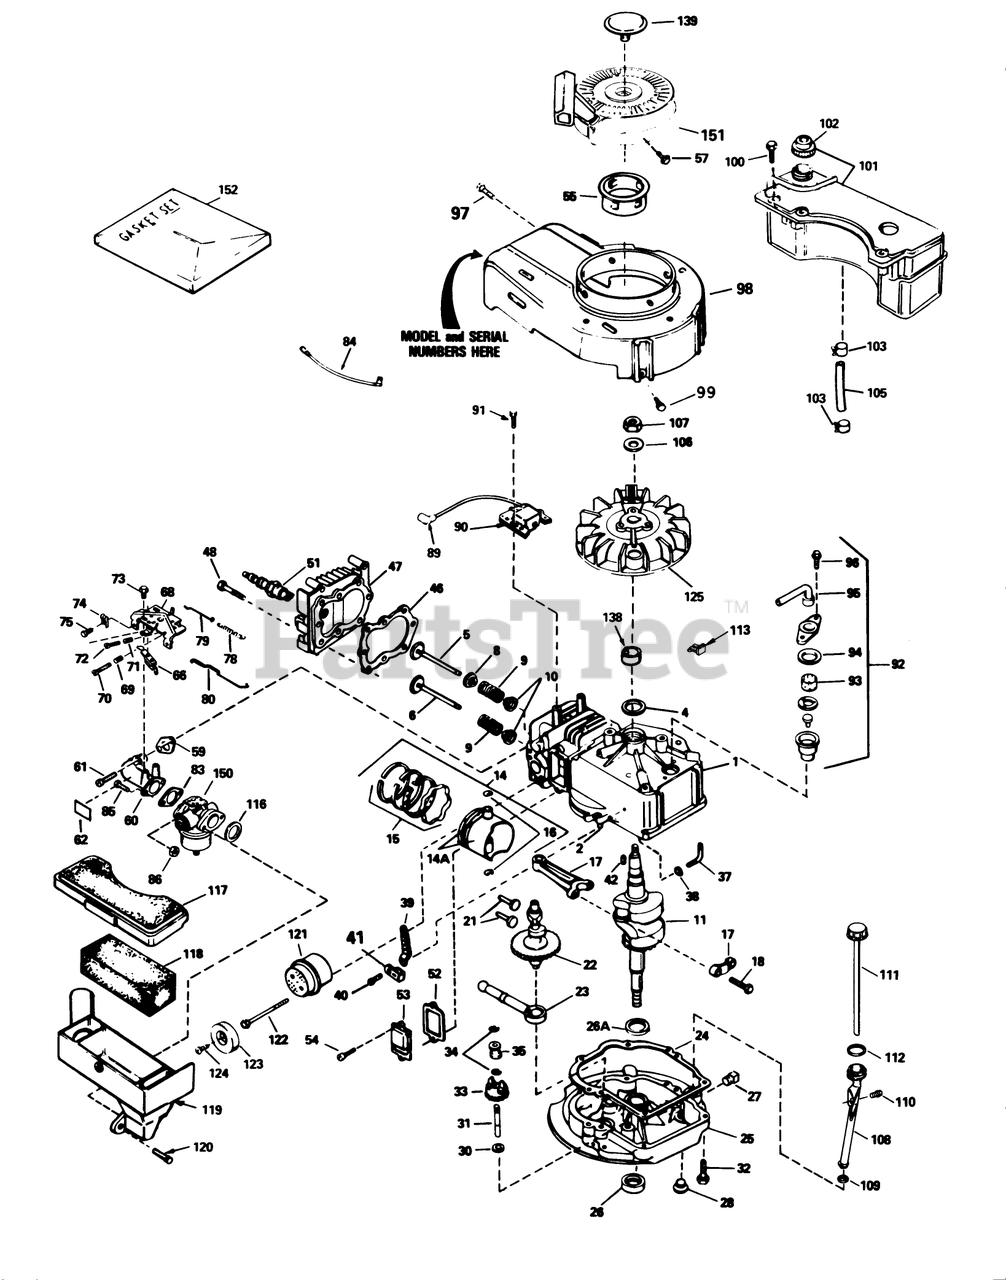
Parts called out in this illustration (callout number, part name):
1	Cylinder Assy. (Incl. #24)
2	Pin-Dowel
4	Seal-Oil
5	Valve, Intake (Std.) (Incl. Ref. #40)
5	Valve, Intake (1/32" oversize)(Incl. No. 40)
6	Valve, Exhaust (Std.)(Incl. No. 40)
6	Valve, Intake (1/32" oversize)(Incl. No. 40)
8	Seal Assy., Intake
9	Spring-Valve
10	Cap-Valve, Spring
11	Crankshaft
14	Piston-Pin Ring Assy. (Std.)(Incl. Ref. #16A, 17 18)
14	Piston-Pin Ring Assembly (.010 oversize)(Incl. Ref. #16A, 17 18)
14	Piston, Pin Ring Assy. (.020 Oversize)(Incl. Ref. #13A, 14, 15)
14A	Piston Pin Assy. (Std.)(Incl. Ref. #14)
14A	Piston Pin Assembly (.010 oversize)(Incl. Ref. #18)
14A	Piston Pin Assy. (.020 Oversize) (Incl. Ref. #14)
15	Ring Set-Piston (Std.)
15	Ring Set, Piston(.0100versize)
15	Ring Set (.020" OS)
16	Ring-Retaining, Piston Pin
17	Rod Assy., Connecting (Incl. Ref. #17)
18	Bolt-Rod, Connecting
21	Lifter-Valve
22	Camshaft(Mech.Comp. Release)
23	Oil Pump ASM
24	Gasket
25	Flange-Mounting (Incl. Ref. #26, 27 39)
26	Seal-Oil
26A	Washer-Thrust
27	Plug-Pipe
28	Plug Oil Drain
30	Washer-Flat
31	Shaft-Governor
32	Screw (1/4-20 x 1-1/4)
33	Governor Gear ASM
34	Ring-Retaining
35	Spool-Governor
37	Rod, Governor (Incl. No. 36)
38	Washer-Flat
39	Governor Lever
40	Screw
41	Clamp-Lever, Governor
42	Key-Flywheel
46	63573 GIL 42 SNWTHW
47	Head-Cylinder
48	Screw (5/16-18x1-1/2)
51	Spark Plug-Resistor (R J19 L M)
52	Gasket-Breather
53	Cover-Valve
54	Screw
55	Hub-Starter
57	Screw, Hex Hd.
59	Gasket-Intake
60	Pipe-Intake (Incl. Ref. #59)
61	Screw (1/4-20 x 1)
62	Decal-Primer
66	Terminal
68	Control Assy.-Remote Speed (Incl. Ref. #69 thru 72 76)
69	61709/GIL1515A/95-5
70	Screw
71	Spring-Compression
72	Screw
73	Screw (10-24 x 9/16)
74	Conduit
75	Screw (10-32 x 3/8)
78	Spring Governor
79	2035A67 ADD.ASSEMBL
80	Link-Throttle
83	Gasket
84	Wire-Ground
86	Nut and Lock Washer (1/4-28)
89	Cover-Spark Plug
90	Solid State
91	Screw
92	Breather Assy. (Incl. Ref. #46 thru 51)
93	Element-Breather
94	Gasket-Breather
95	Tube, Breaker
96	Screw (10-24 x 9/16)
97	Screw (10-24 x 9/16)
98	Housing-Blower
99	Screw (1/4-20 x 1/2)
100	Screw (10-32 x 35/64)
101	Tank Assembly-Fuel (Incl. Ref. #102)
102	Cap-Fuel
103	Clamp-Line, Fuel
105	Line-Fuel
106	Washer-Belleville
107	Nut-Flywheel
108	Oil Fill Tube
109	Gasket
110	Screw (10-32 x 1/2)
111	Dipstick
112	O-Ring
113	Clip-Wire
116	Gasket-Cleaner, Air
117	Cover-Air Cleaner
118	Filter-Air Cleaner
119	Body Air cleaner
120	Screw
121	Muffler (Incl. Ref. #122)
122	Screw
123	Cover-Muffler
124	Screw (8-32 x 3/8)
125	Flywheel
138	Spacer
139	Plug Starter
150	Carburetor (Incl. Ref. #83)
151	Starter-Rewind
152	Gasket Set
